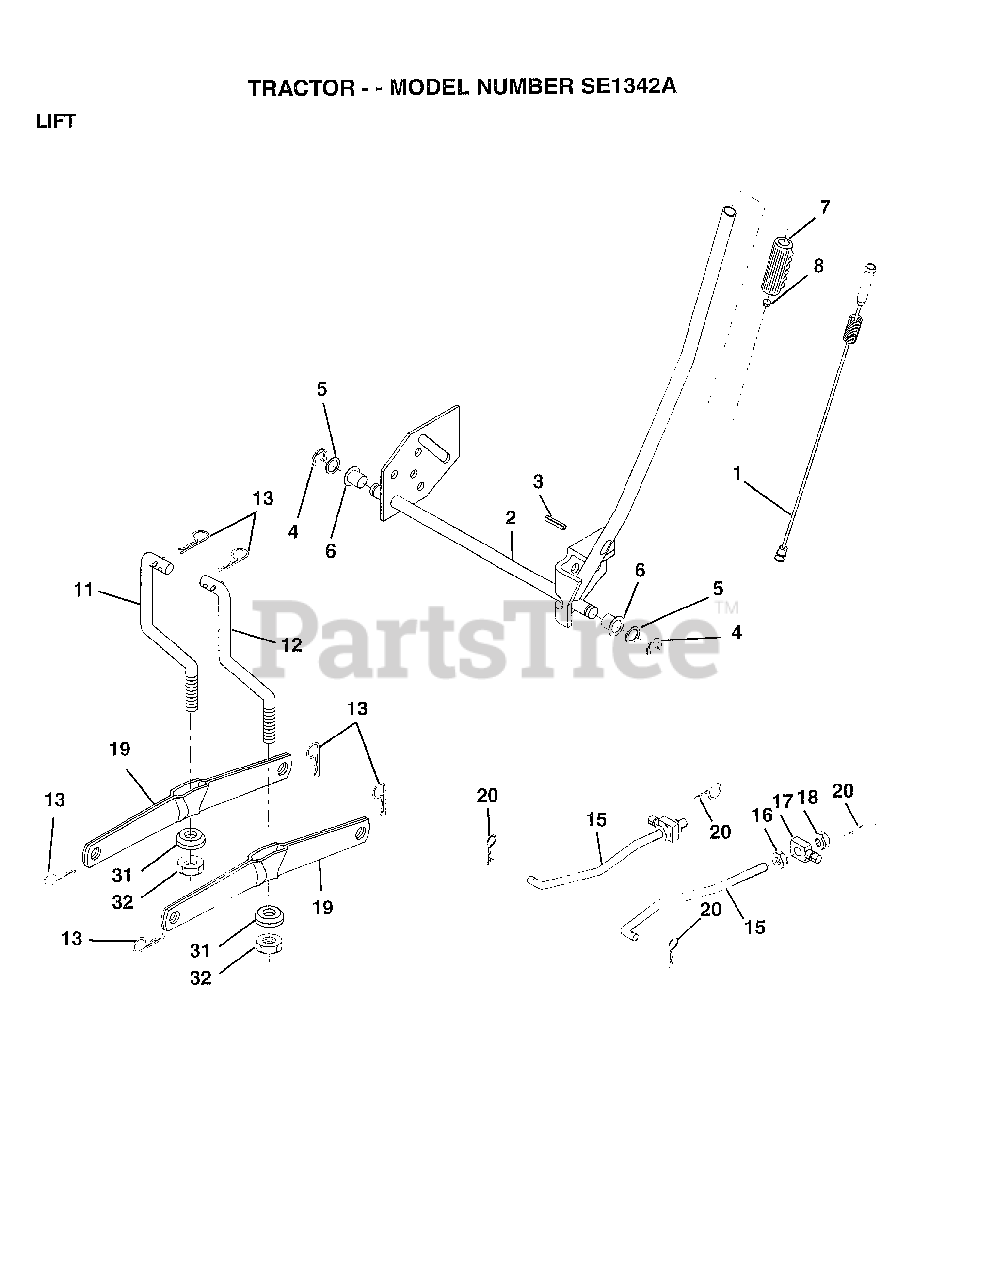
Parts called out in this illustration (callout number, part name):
1	WIRE ASM W.SPRING
2	"SHAFT ASM LIFT,RH"
3	PIN-GROOVE LT
5	WASHER
6	NYLON BEARING
7	GRIP
15	LINK.FRONT
16	NUT
17	TRUNION
18	NUT.LK.W/WSH.1/2.
19	ARM SUSP REAR
20	RETAINER.SPRING
31	BEARING PVT LH
32	NUT.CROWNLOCK.3/8
